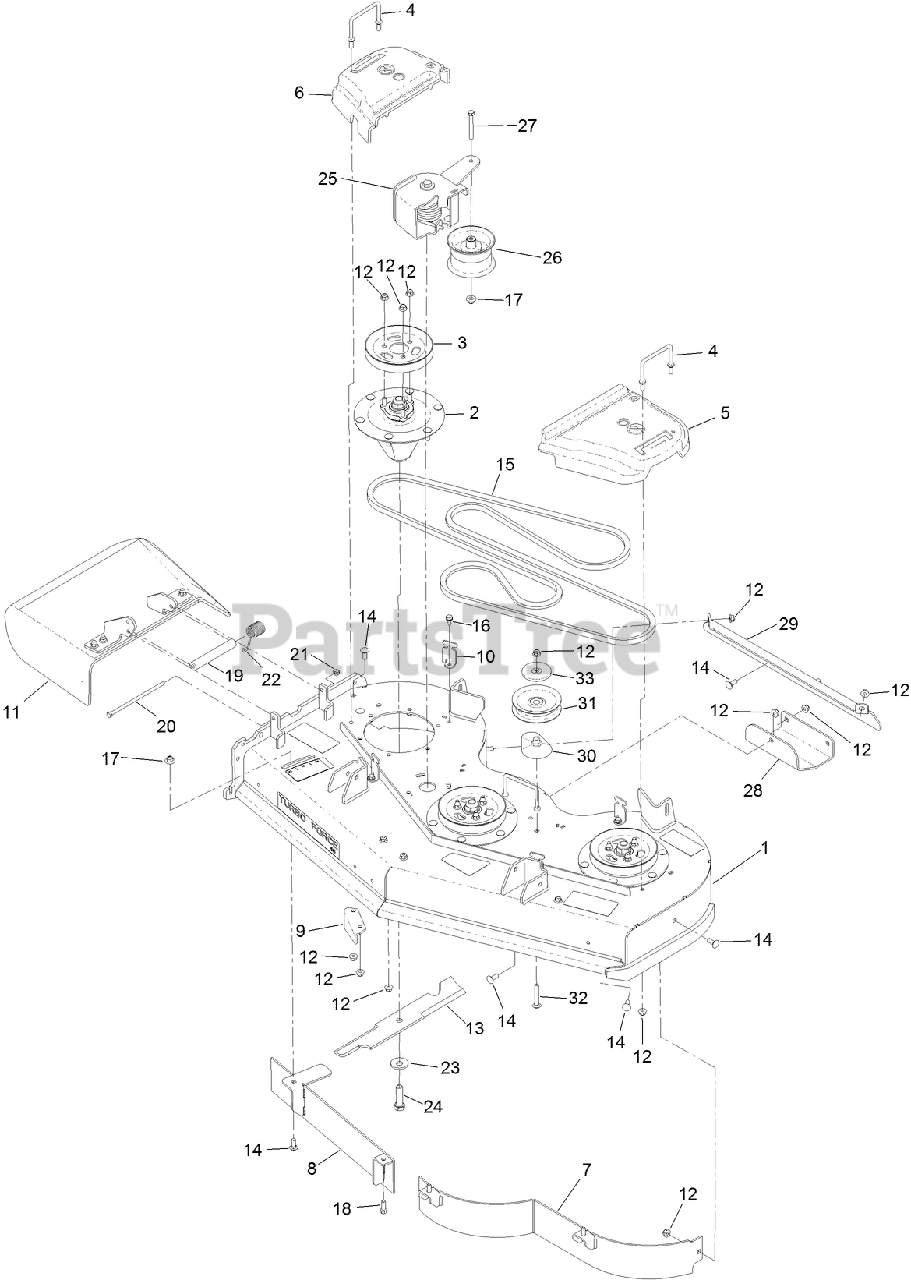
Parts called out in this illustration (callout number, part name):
1	DECK ASM
2	SPINDLE ASM
3	PULLEY
4	WIREFORM-COVER
5	COVER-BELT, LH
6	COVER-BELT, RH
7	48 INCH BAFFLE ASM
9	BAFFLE-DISCHARGE
10	BRACKET-COVER
11	DEFLECTOR ASM
12	NUT-HF, NI
13	BLADE-16.5 INCH (HIGH FLOW)
14	SCREW-HH
15	BELT-V
16	SCREW-HWHTF
17	NUT-FLANGE, NI
19	SPACER
20	SCREW-HH
21	NUT-HF, NI
22	SPRING-TORSION
23	WASHER-BLADE BOLT, HEAVY
24	SCREW-BLADE
26	PULLEY-IDLER
27	SCREW-HH
29	BRACKET-SKID
30	SPACER-PULLEY
31	PULLEY-IDLER, FLAT
32	SCREW-CARR
33	SHIELD-DUST
